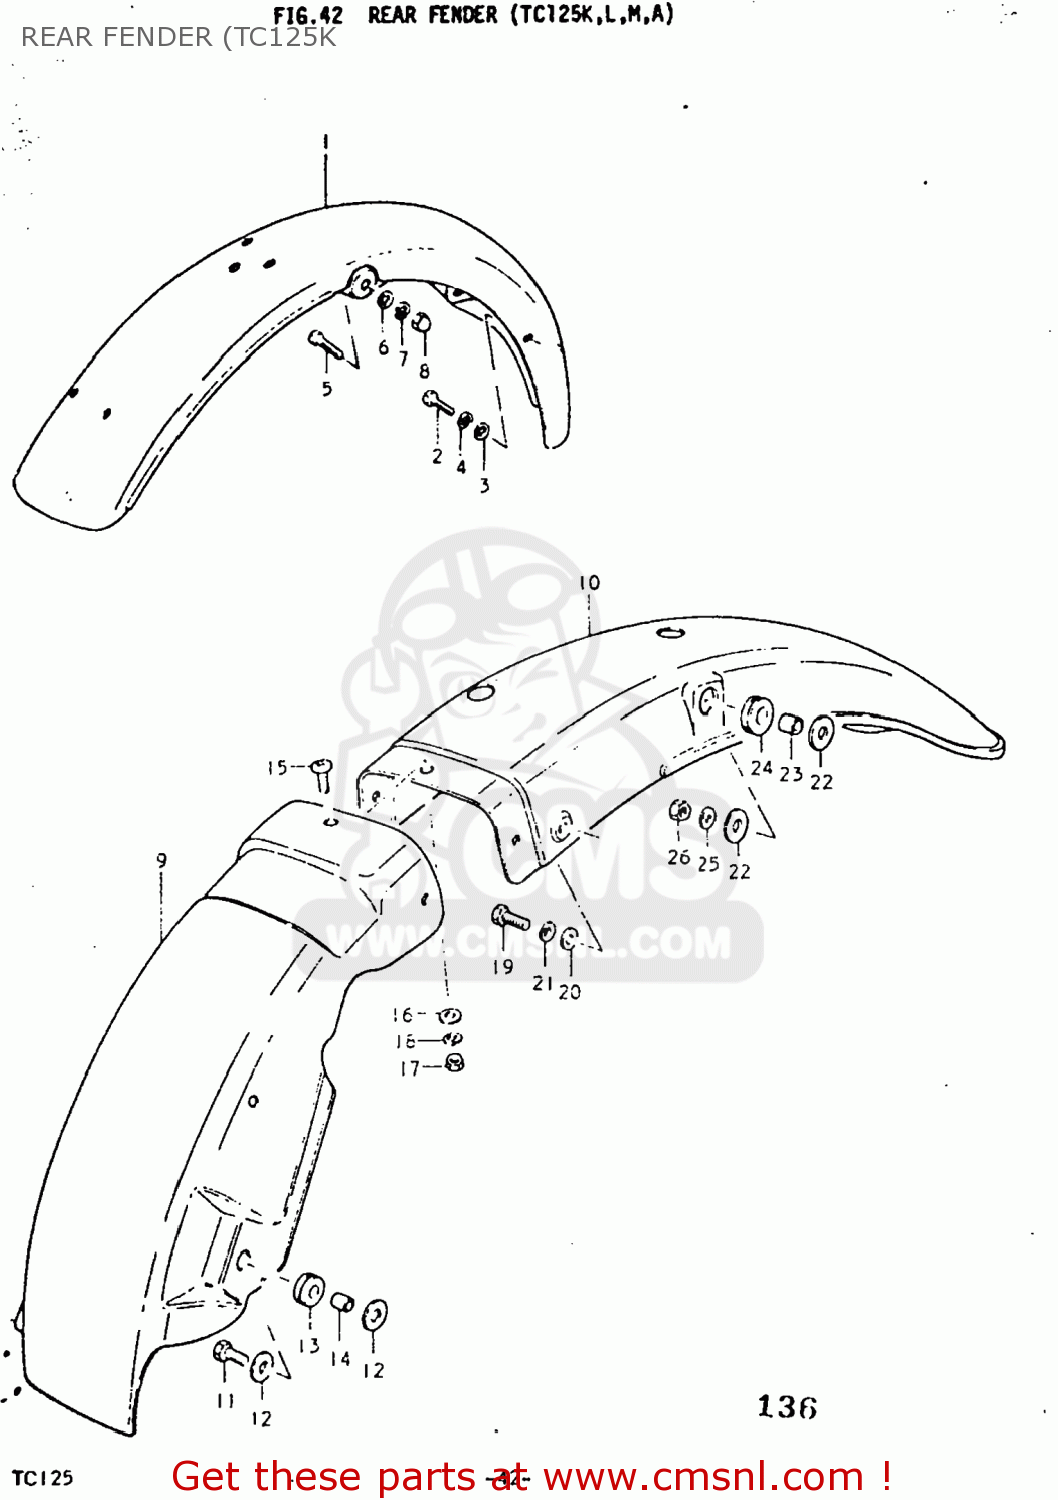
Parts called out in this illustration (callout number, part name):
1	FENDER,REAR
2	BOLT
3	WASHER
4	LOCK WASHER
5	BOLT
6	WASHER
7	LOCK WASHER
8	NUT
9	FENDER,REAR
10	FENDER,REAR
11	BOLT
12	WASHER (6.5X20X1.2)
13	CUSHION
14	SPACER(6.1X9X7.5)
15	SCREW
16	WASHER 5MM
17	NUT
18	LOCK WASHER
19	BOLT
20	WASHER
21	LOCK WASHER
22	WASHER(10.3X25X1.5
23	SPACER
24	CUSHION
25	LOCK WASHER
26	NUT
